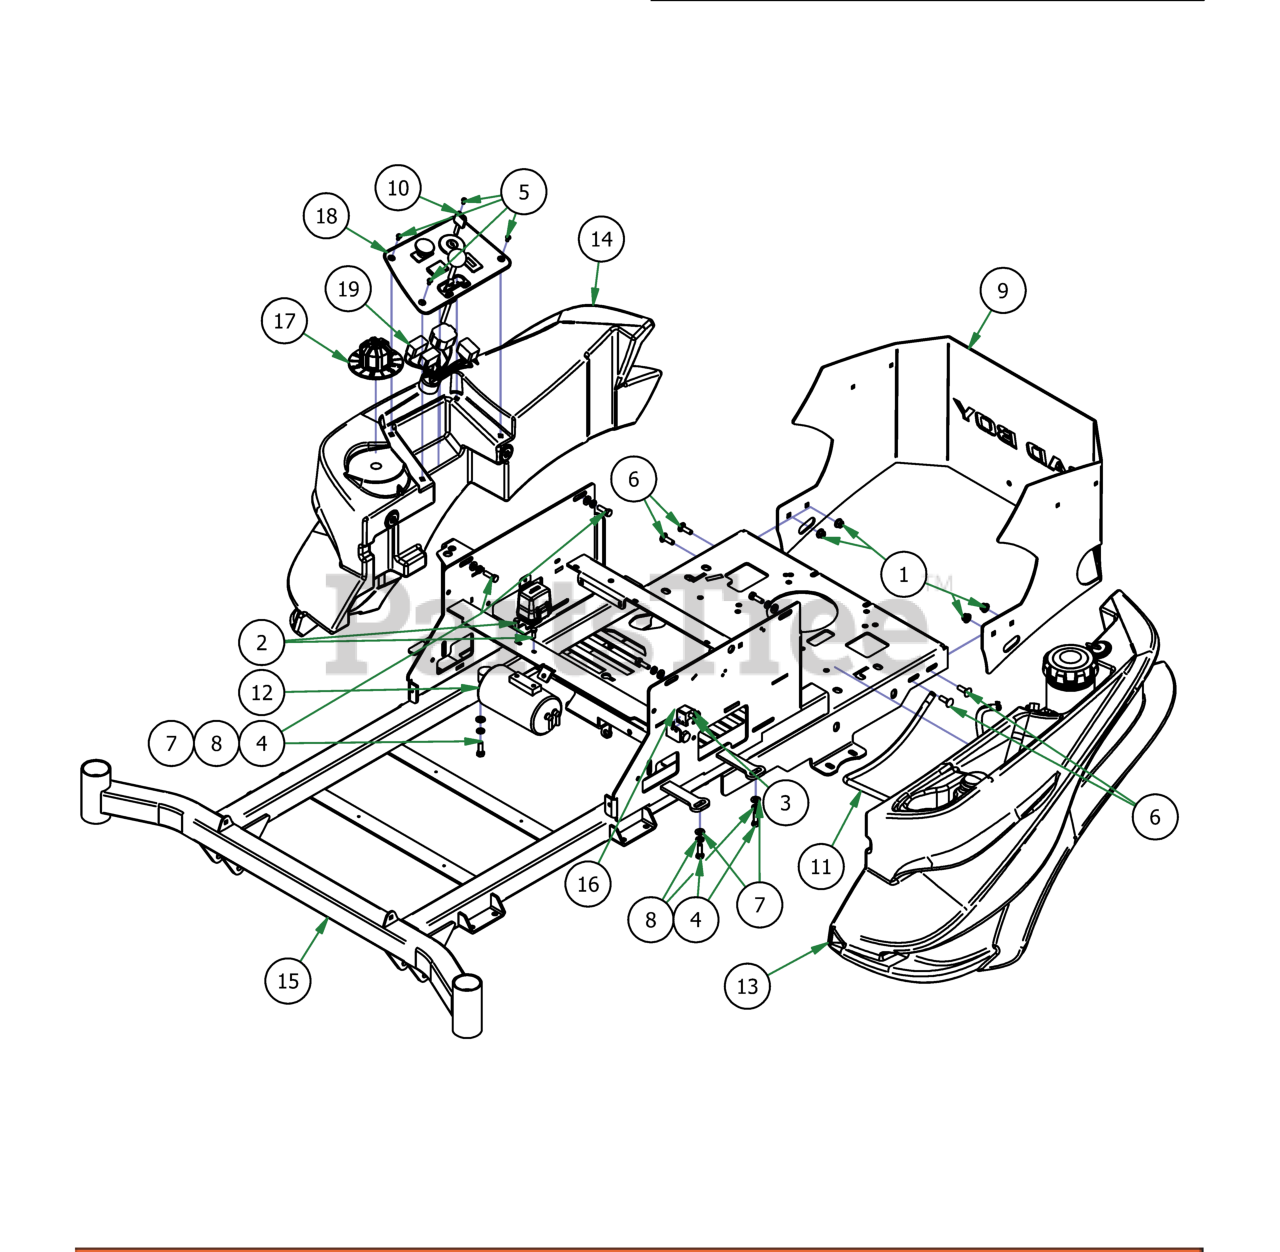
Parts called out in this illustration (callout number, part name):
1	5/16" Nylon Flange Nut
2	M6-1.0 X 16MM Hex Bolt
3	12-24x 1/2 HWH Bolt
4	5/16" x 1" Bolt
5	10-32 x 3/8" Button Socket Head Bolt
6	5/16" x 1" Carriage Bolt
7	5/16" Flat Washer
8	5/16" Lock Washer
9	2017 ZT Rear Plate
10	Ignition Key
11	37" Fuel Line Assembly
12	ZT/Mav EPA Cannister Assy
13	Left Fuel Tank
14	Right Side Console
15	2017 MZ/ZT 54"-60" Frame
16	Safety Switch
17	MZ/ZT Deck Height Dial
18	2019 ZT/Maverick Control Panel Assembly
19	Wiring Harness
